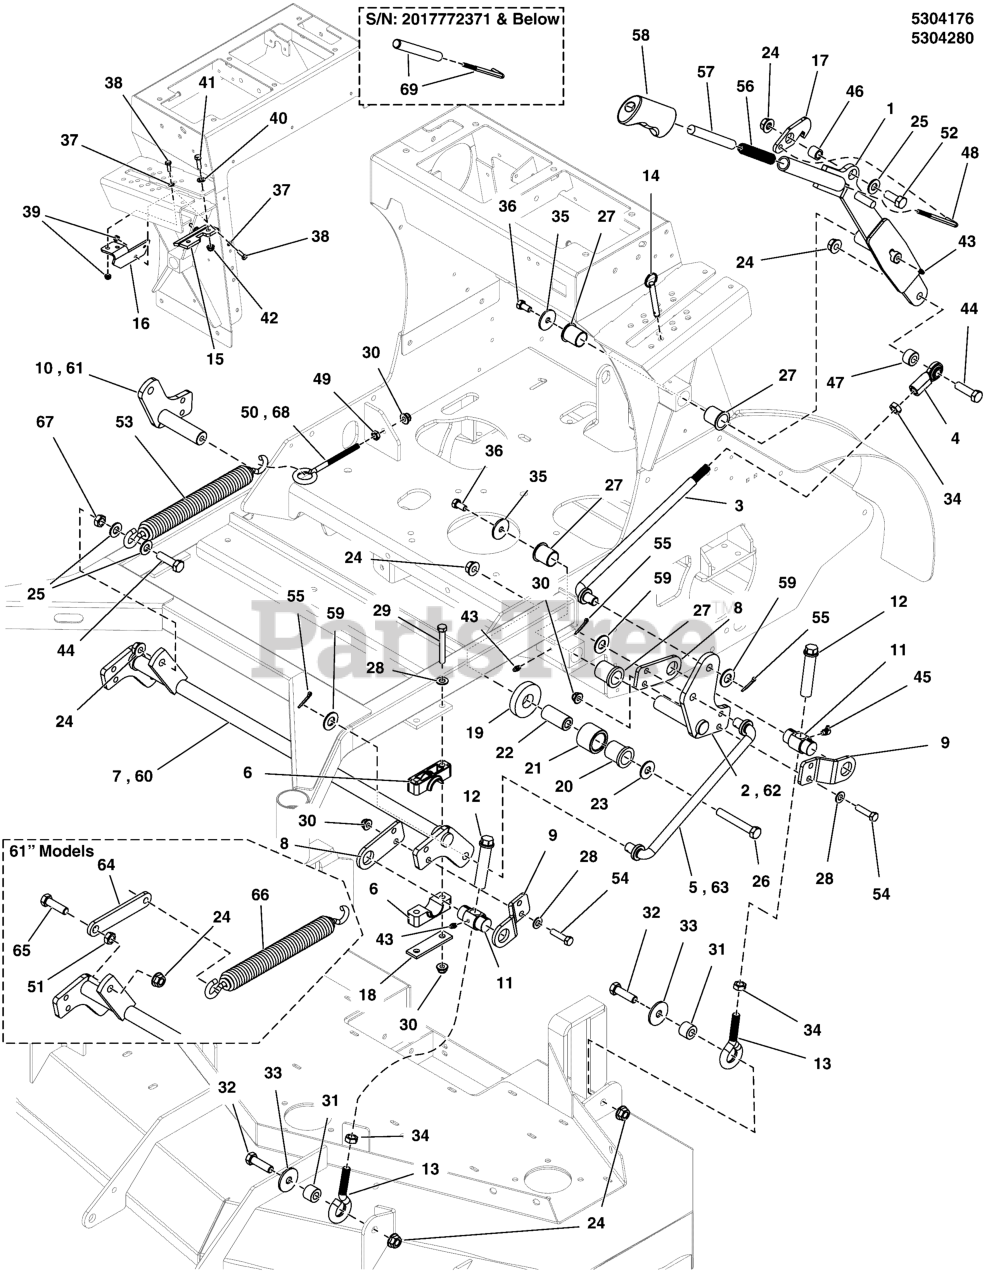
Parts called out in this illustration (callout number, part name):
1	WELD, DECK LIFT, STAND ON - BLK
3	ROD, MAIN DECK LIFT, STAND-ON
4	JOINT-BALL .500-20 THD .500ID, CLR ZINC
6	PIVOT BLOCK, PLASTIC
7	WELD, SHAFT, DECK LIFT - BLK
8	BRACKET, INNER TRUNION MNT - BLK
9	BRACKET, OUTER TRUNION MNT - BLK
10	WELD, RH REAR PIVOT, STAND ON - BLK
11	PIVOT, DECK LIFT TRUNION, GREASABLE
12	ADJUSTER, HEIGHT
13	EYE BOLT, 1/2-20 X 4.25,1.88THRD,1EYE,CZ
14	PIN, HITCH, 3/8" DIA X 2.5" EL, CZ
15	PLATE, LATCH GUIDE - BLK
16	PLATE, BRACKET, DECK LIFT SUPPORT - BLK
17	PLATE, LATCH, PUSH BUTTON LIFT - BLK
18	PLATE, PIVOT BLOCK SUPPORT - BLK
19	WASHER, FRICTION
20	BUSHING, FLANGE
21	ROLLER, DECK HEIGHT
22	SPACER, .52 X 1.00 X 2.09 - SS
23	WASHER, 1/2 USS
24	NUT, Hex Flange, Nylock, 1/2-13
25	WASHER, 1/2 SAE
26	BOLT, 1/2-13 X 3-1/4, HEX HD, GD5, CZ (SV)
27	BUSHING, 1.00 X 1.13 X 1.38, PLASTIC
28	WASHER, 3/8 SAE
29	BOLT, 3/8-16 X 2-3/4" GD5 CZ
30	NUT, 3/8-16 HEX NYLOCK FLANGE
31	SPACER, .52 X 1.00 X .75, CZ
32	BOLT, 1/2-13 X 1-3/4 GD5 CZ
33	WASHER, .52 X 1.75 X .14, CZ
34	NUT, 1/2-20 HEX JAM
35	WASHER, .390 X 1.50 X .109, CZ
36	BOLT, 3/8-16 X 3/4, PLT W/PATCH
37	WASHER, 1/4 SAE
38	BOLT, 1/4-20 X 3/4 GD5 CZ
39	NUT, 1/4-20 HEX NYLOCK FLANGE
40	WASHER, 5/16" SAE
41	BOLT, 5/16-18 X 1 GD5 CZ
42	NUT, 5/16-18 HEX NYLOCK FLANGE
43	GREASE FITTING, 1/4-28 STRAIGHT
44	BOLT, 1/2-13 X 2-1/4" GD5 CZ
45	GREASE FITTING, 1/4-28, 90 DEGREE
46	SPACER, .50 X .75 X .66, CZ
47	SPACER, .52 X 1.00 X .63, CZ
48	ROD, DECK LIFT LATCH
49	NUT, 3/8-16 HEX JAM
50	EYE BOLT, 3/8-16 X 6, 3THRD, 1EYE, CZ
51	NUT, 1/2-13 HEX JAM
52	BOLT, 1/2-13 X 1-1/2 GD5 CZ
53	SPRING-EXT, 1.393 ODX13.25LGX.218WR, BLK
54	BOLT, 3/8-16 X 1-1/2" GD5 CZ
55	PIN, COTTER, 1/8 X 1-1/4
56	SPRING-COMP 0.715ODX 03.85 LG
57	BUTTON, PUSH, DECK LIFT, THREADED
58	GRIP,LIFT LEVER
59	WASHER, 5/8 SAE
60	WELD, SHAFT, DECK LIFT - BLK
61	WELD, RH REAR PIVOT, SRSZ2-61 - BLK
62	WELD, LH REAR PIVOT, SRSZ2-61 - BLK
64	PLATE, SPRING LINK, SRS Z2, 61 - BLK
65	BOLT, 1/2-13 X 2" GD5 CZ
66	SPRING, EXT, 1.50DX12.25X.234WIRE BLK
67	NUT, 1/2-13 HEX, CZ
68	EYE BOLT, 3/8-16 X 6.88, 3THRD, 1EYE
69	KIT, RELEASE BUTTON AND ROD
